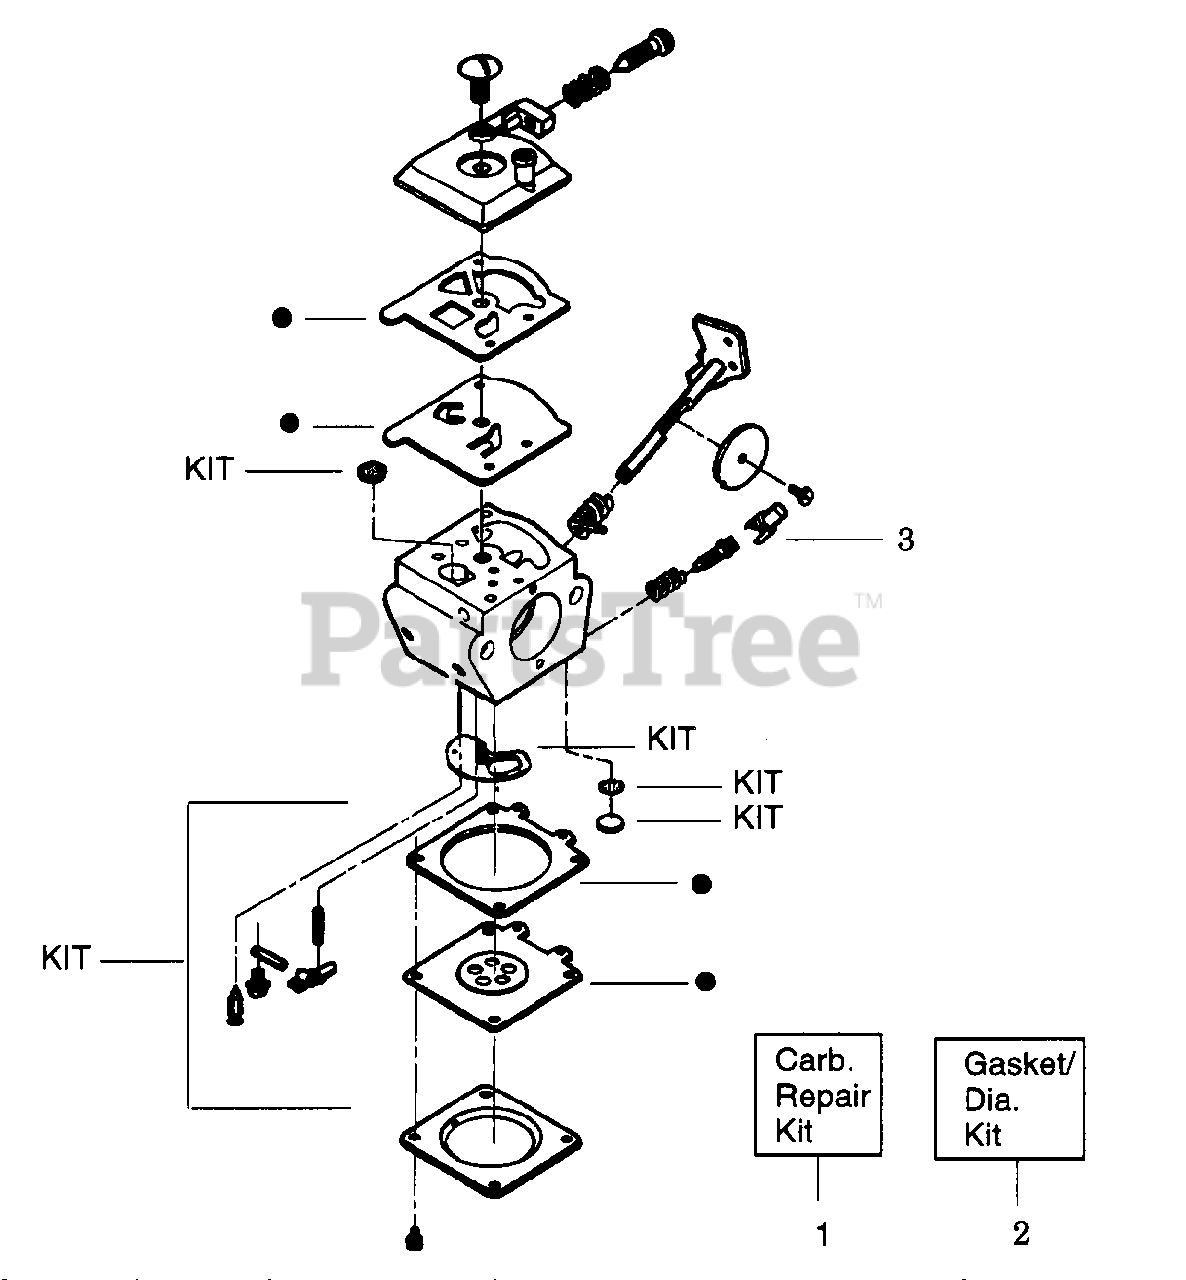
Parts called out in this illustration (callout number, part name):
1	Carburetor Repair Kit, WA-217 (KIT=Indicates Contens)
1	Carburetor Repair Kit, WA-219B (KIT=Indicates Contens)
2	Gasket/Diaphragm Kit, WA-217 ("."=Indicates Contens)
2	Gasket/Diaphragm Kit, WA-219B ("."=Indicates Contens)
3	Limiter Cap
